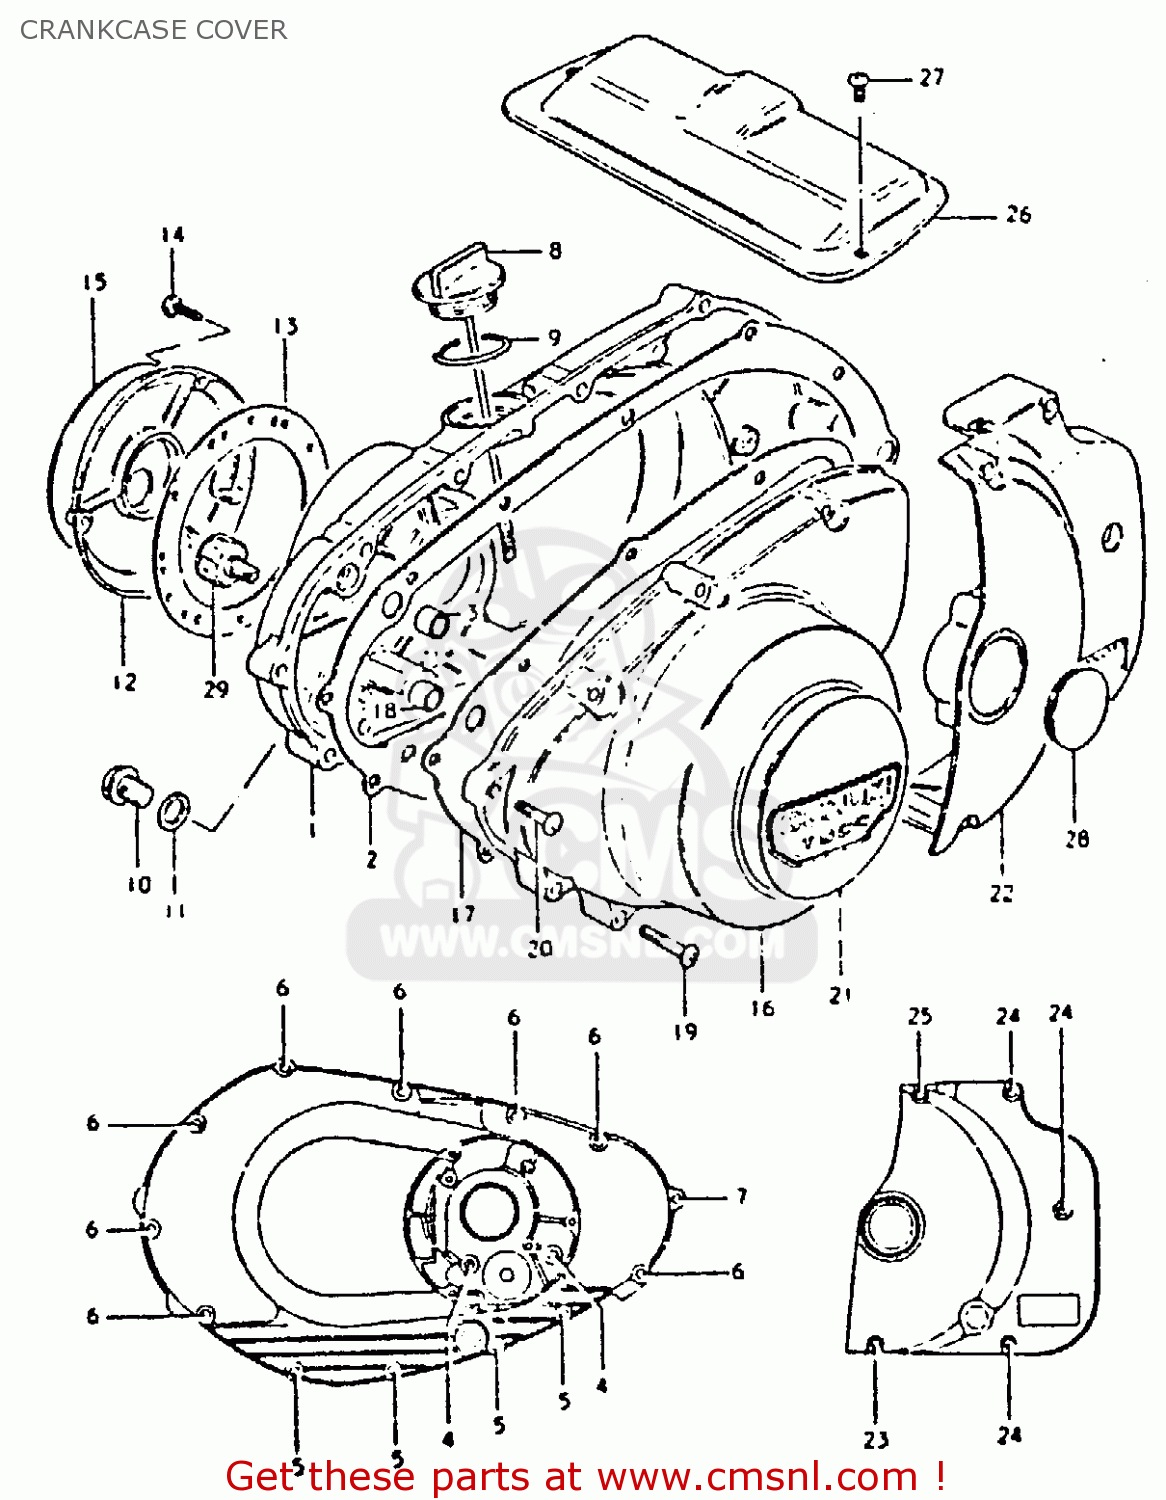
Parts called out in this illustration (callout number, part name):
1	COVER,CLUTCH
2	GASKET,CLUTCH COVER (MCA)
3	PIN
4	SCREW
5	SCREW (6X45)
6	SCREW (6X35)
7	SCREW
8	GAUGE,OIL LEVEL
9	O-RING
10	PLUG (14X12)
11	GASKET(14X19.2X2) (NAS)
12	COVER,CONTACT BREAKER
13	GASKET,CONTACT BREAKER COVER (NAS)
14	SCREW 5X20
15	EMBLEM
16	COVER,MAGNETO
17	GASKET,MAGNETO COVER (MCA)
18	PIN
19	SCREW 6X30
20	SCREW
21	EMBLEM
22	COVER,SPROCKET
23	SCREW 6X60
24	SCREW
25	SCREW 6X30
26	COVER,STARTER MOTOR
27	SCREW
28	CAP(OD:36)
29	SWITCH ASSEMBLY
